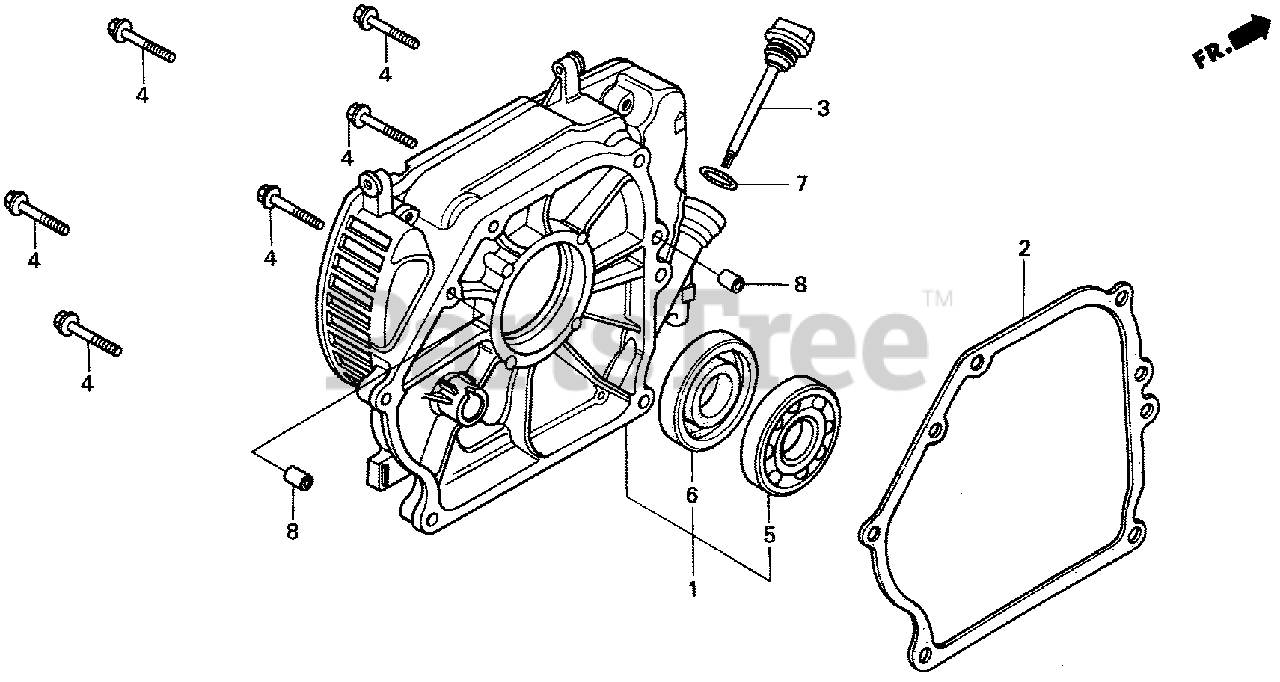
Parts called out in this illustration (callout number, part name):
1	COVER ASSY., CRANKCASE
2	GASKET, CASE COVER
3	CAP, OIL FILLER
4	BOLT, FLANGE (8X32)
5	BEARING, RADIAL BALL (6205)
6	OIL SEAL (25X41X6)
7	O-RING (16MM)
8	PIN A, DOWEL (8X14)
